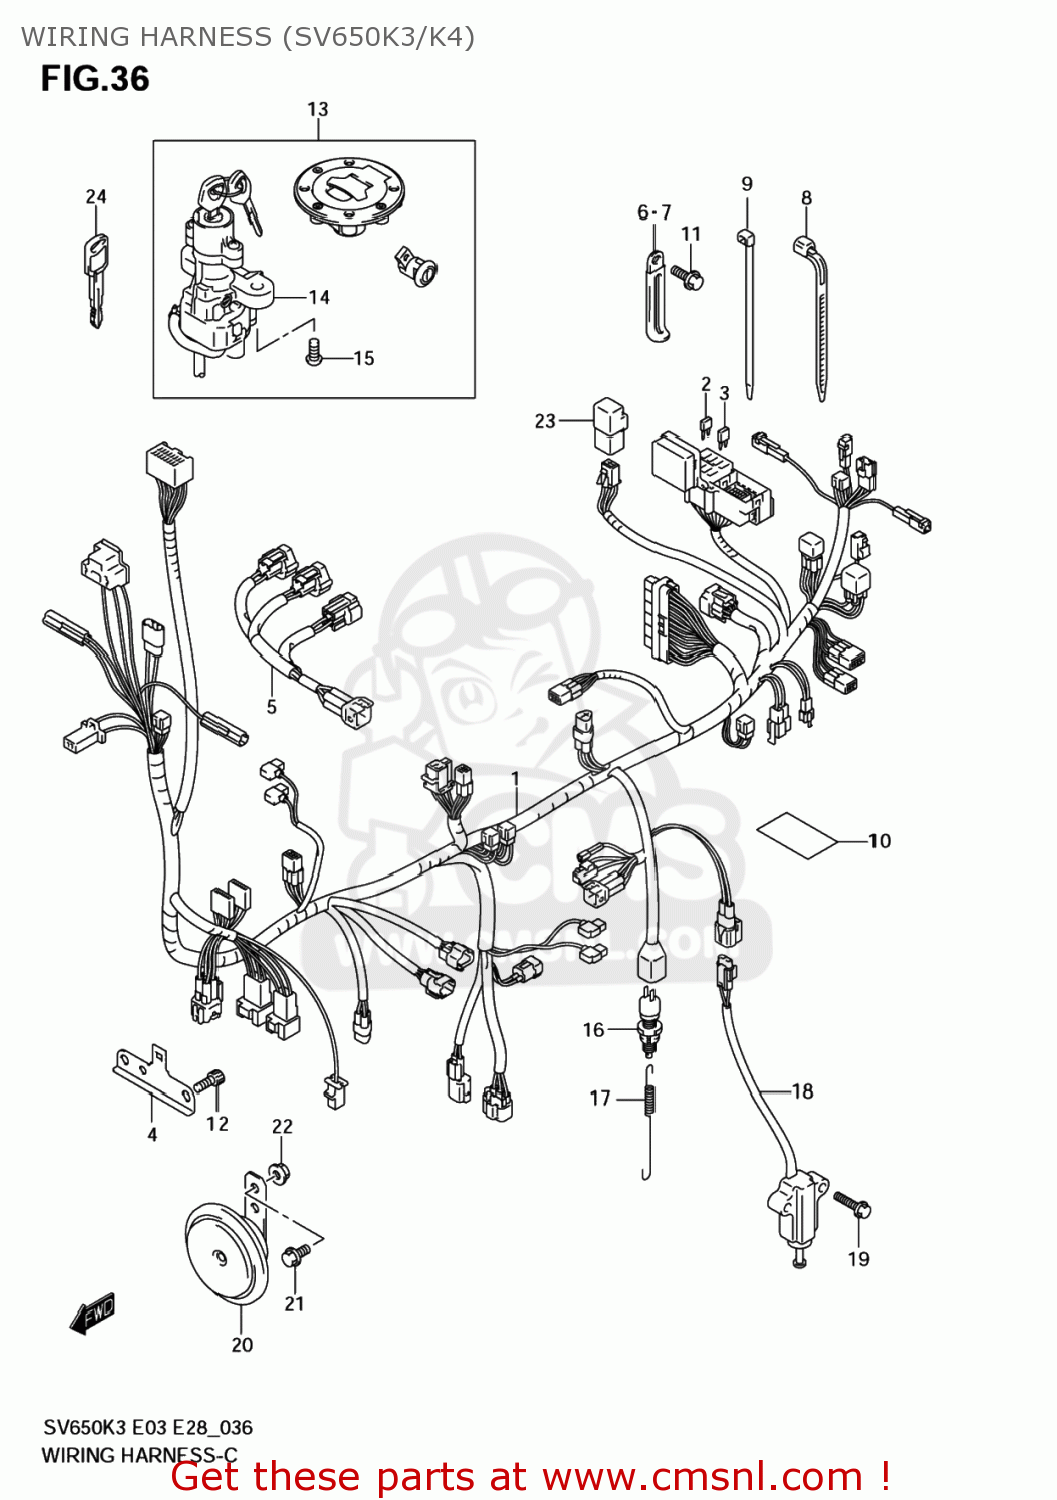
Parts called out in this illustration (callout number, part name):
1	HARNESS, WIRING
2	FUSE(10A)
3	FUSE(15A)
4	HOLDER,COUPLER
5	WIRE,INJECTOR LEAD
6	CLAMP(L:45)
7	CLAMP(L:80)
8	CLAMP(L:125)
9	CLAMP(L:145)
10	TAPE,WIRING HARNESS(28X50X0.13
11	BOLT
12	BOLT,VAC.PIPE
13	LOCK SET
14	LOCK ASSY,STEE
15	BOLT(8X20)
16	SWITCH ASSY,STOP LAMP
17	SPRING
18	SWITCH ASSY,SIDE STAND WARNING
19	BOLT(6X25)
20	HORN ASSY
21	BOLT
22	NUT
23	RELAY ASSY
24	KEY,BLANK
